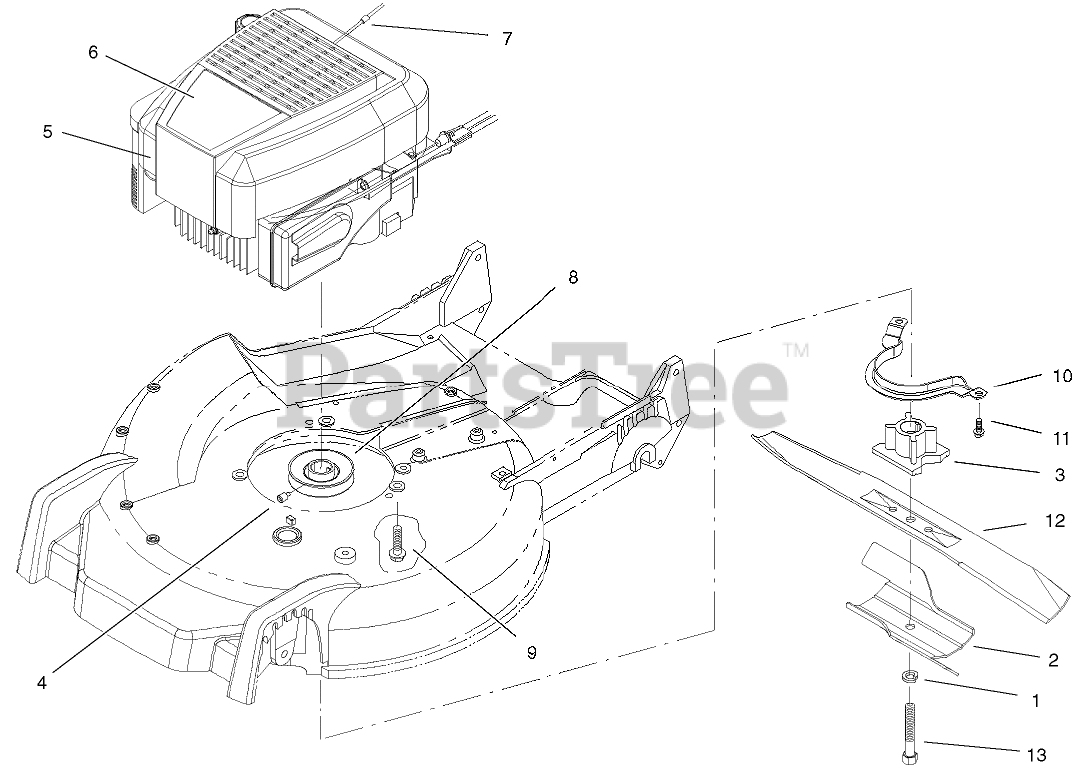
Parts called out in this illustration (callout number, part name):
1	WASHER-LOCK
2	ACCELERATOR-BLADE
3	RETAINER-BLADE
4	SCREW-SET
6	DECAL - RECOIL - QUIET I/C
7	STOP-ROPE
8	PULLEY
9	SCREW-HWH
10	BRACKET-GUIDE, BELT
11	SCREW-HWHTF
12	BLADE
13	SCREW-BLADE
